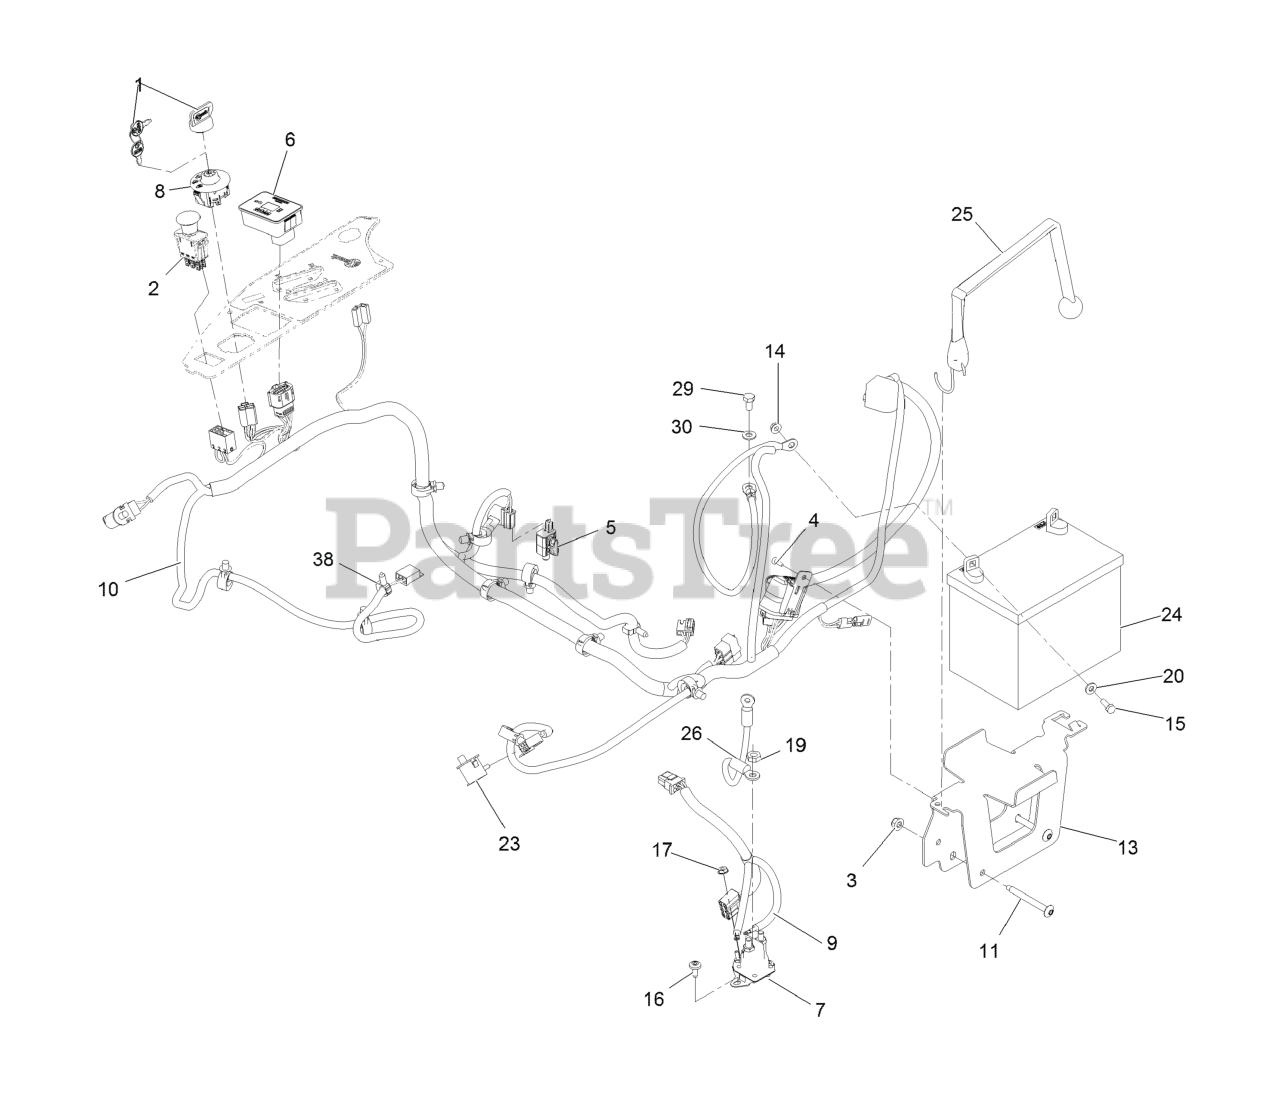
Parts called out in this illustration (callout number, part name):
1	KEYS-IGNITION (SPARE PAIR
1	KEY-IGNITION
2	SWITCH-PTO
3	NUT-HF, NI
4	SCREW-FORMING, THREAD
6	MODULE ASM
7	SOLENOID
8	SWITCH-IGNITION
9	ADAPTER-HARNESS, WIRE
10	HARNESS-WIRE
11	SCREW-TORX
13	TRAY-BATTERY
15	SCREW-HH
16	SCREW-TORX
17	NUT-KEPS
19	NUT-JAM
20	WASHER-FLAT
23	SWITCH-BAIL
24	Battery-195 CCA, Wet
25	STRAP-BUNGEE
26	CABLE-BATTERY, POSITIVE
29	SCREW-HH
30	WASHER-PLAIN
38	CLIP-HARNESS
